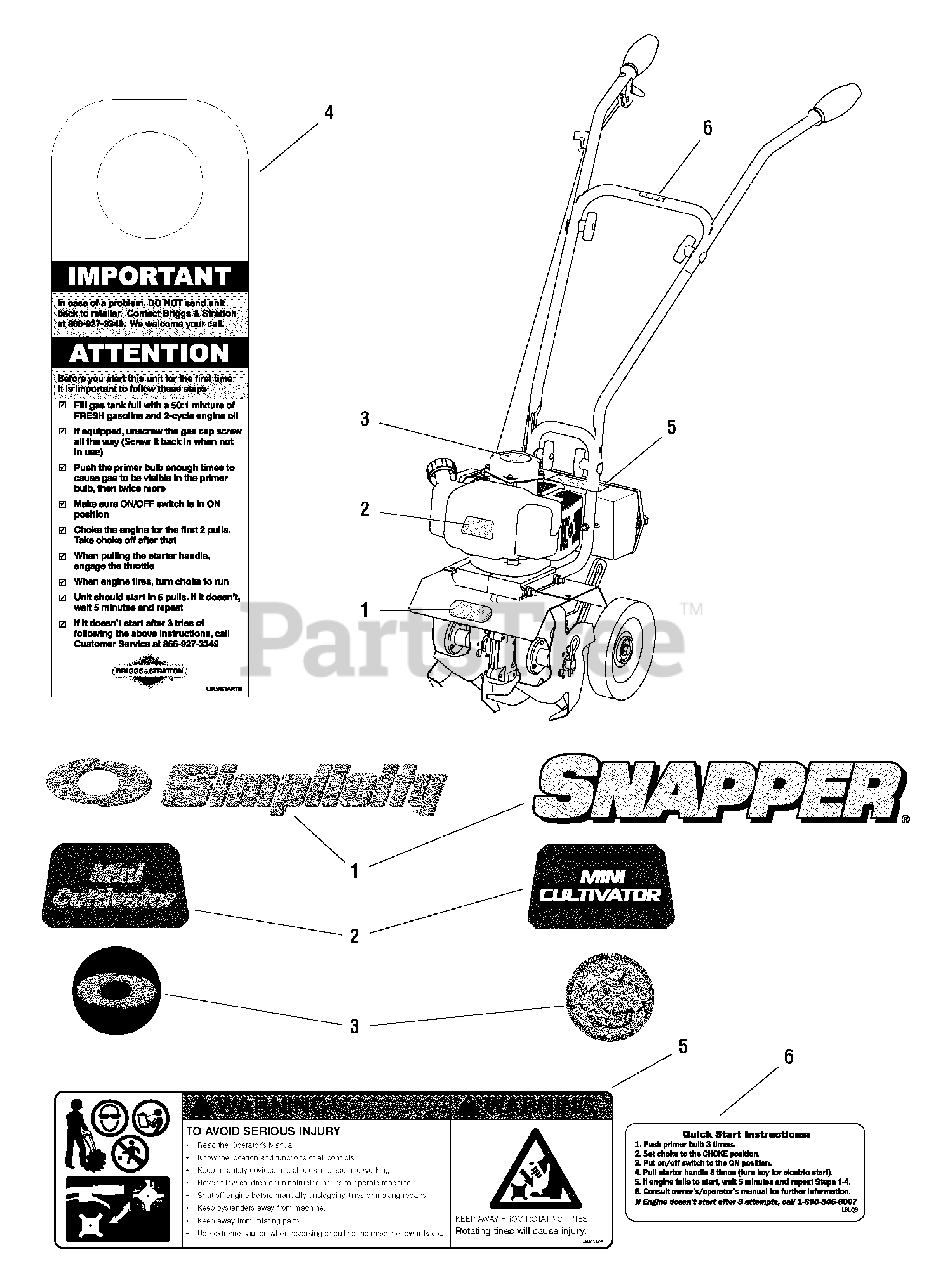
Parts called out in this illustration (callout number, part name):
1	DECAL, Simplicity, Front Panel, 9.12 x 1.38
1	DECAL, Snapper, Front Panel, 8.62 x 1.68
2	DECAL, Simplicity, Top Shroud, 3.34 x 1.91
2	DECAL, Snapper, Top Shroud, 3.33 x 1.91
3	DECAL, Simplicity Logo, Top Circle, 2 x 2
3	DECAL, Snapper Logo, Top Circle, 2 x 2
4	DECAL, Important/Attention Hanger, 2.9863 x 9.0615
5	DECAL, Warning, Avoid Injury, Rotating Tines
6	DECAL, Quick Start Instructions
